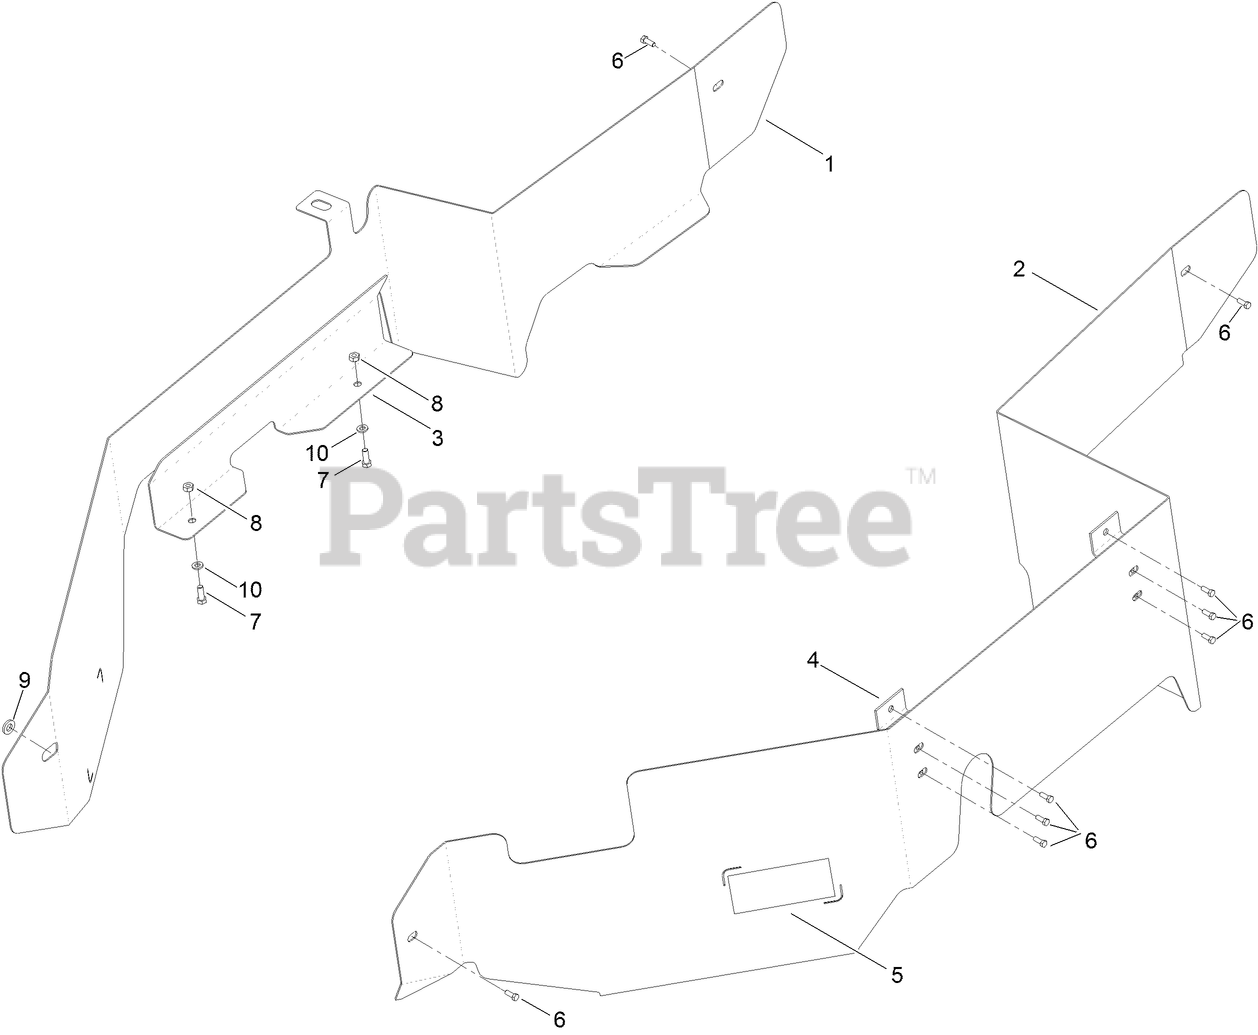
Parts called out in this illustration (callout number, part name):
1	GUARD BELT RH
2	GUARD BELT LH
3	GUARD-DECK BELT COVER
4	BRACKET, FRAME MOUNTING
5	DECAL-WARNING
6	SCREW-TAP
7	SCREW-HH
8	NUT-NYLOC
9	WASHER
10	WASHER PLAIN
